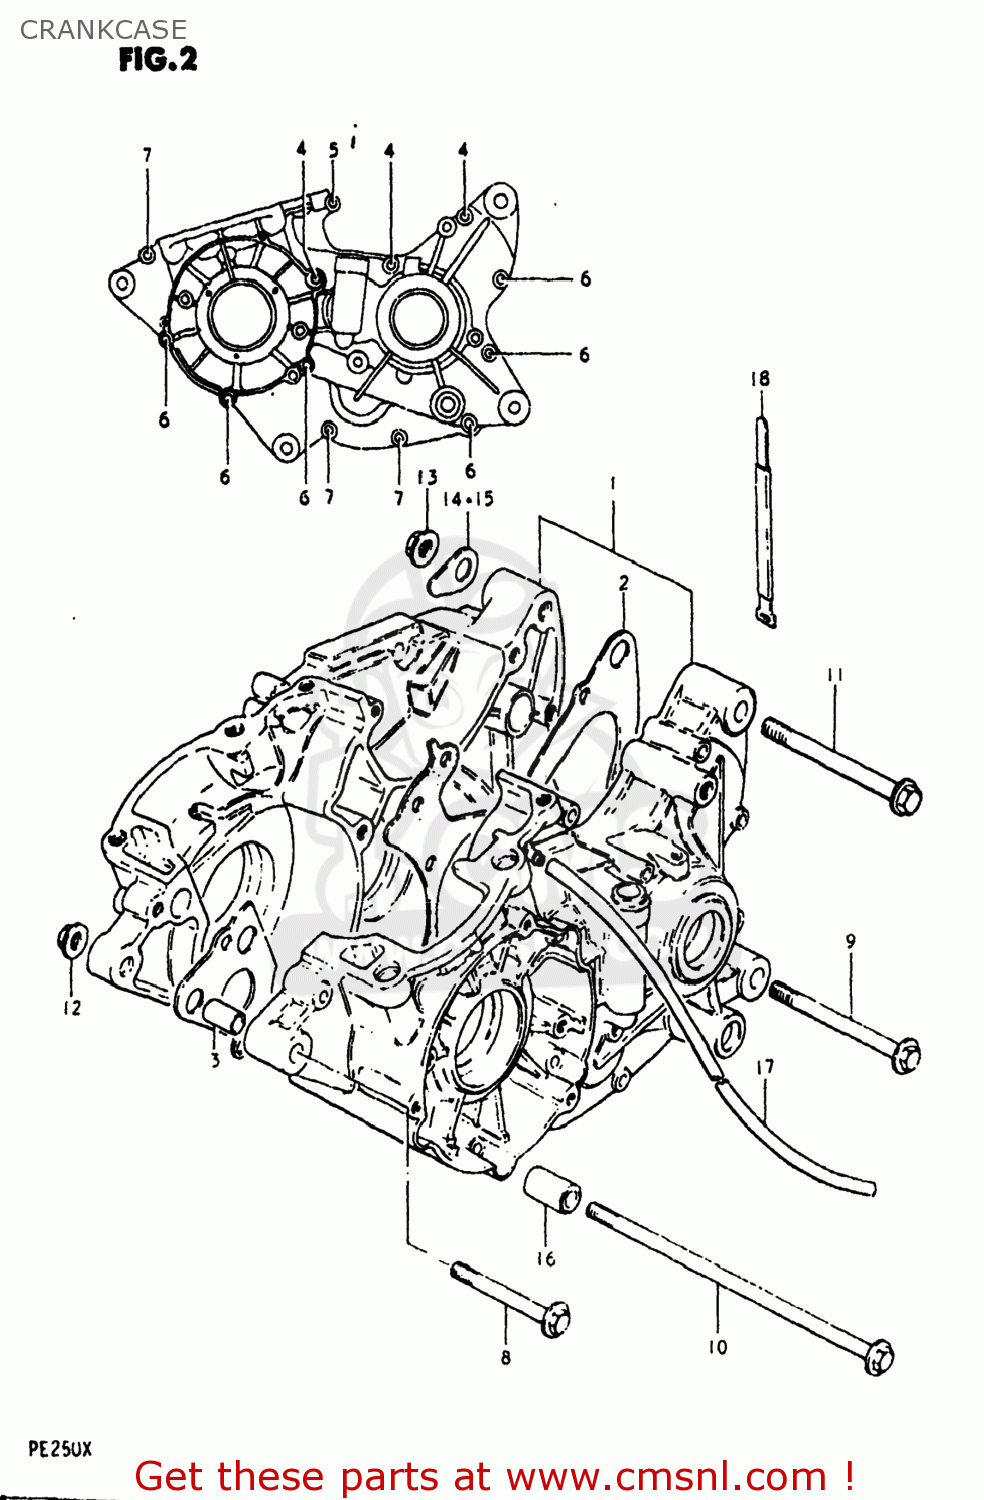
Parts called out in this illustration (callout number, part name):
1	CRANKCASE SET
2	GASKET,CRANKCASE (MCA)
3	PIN
4	SCREW 6X65
5	SCREW
6	SCREW
7	SCREW
8	BOLT(8X67)
9	BOLT
10	BOLT
11	BOLT
12	NUT
13	NUT
14	WASHER
15	WASHER
16	SPACER(8.6X16X26)
17	HOSE
